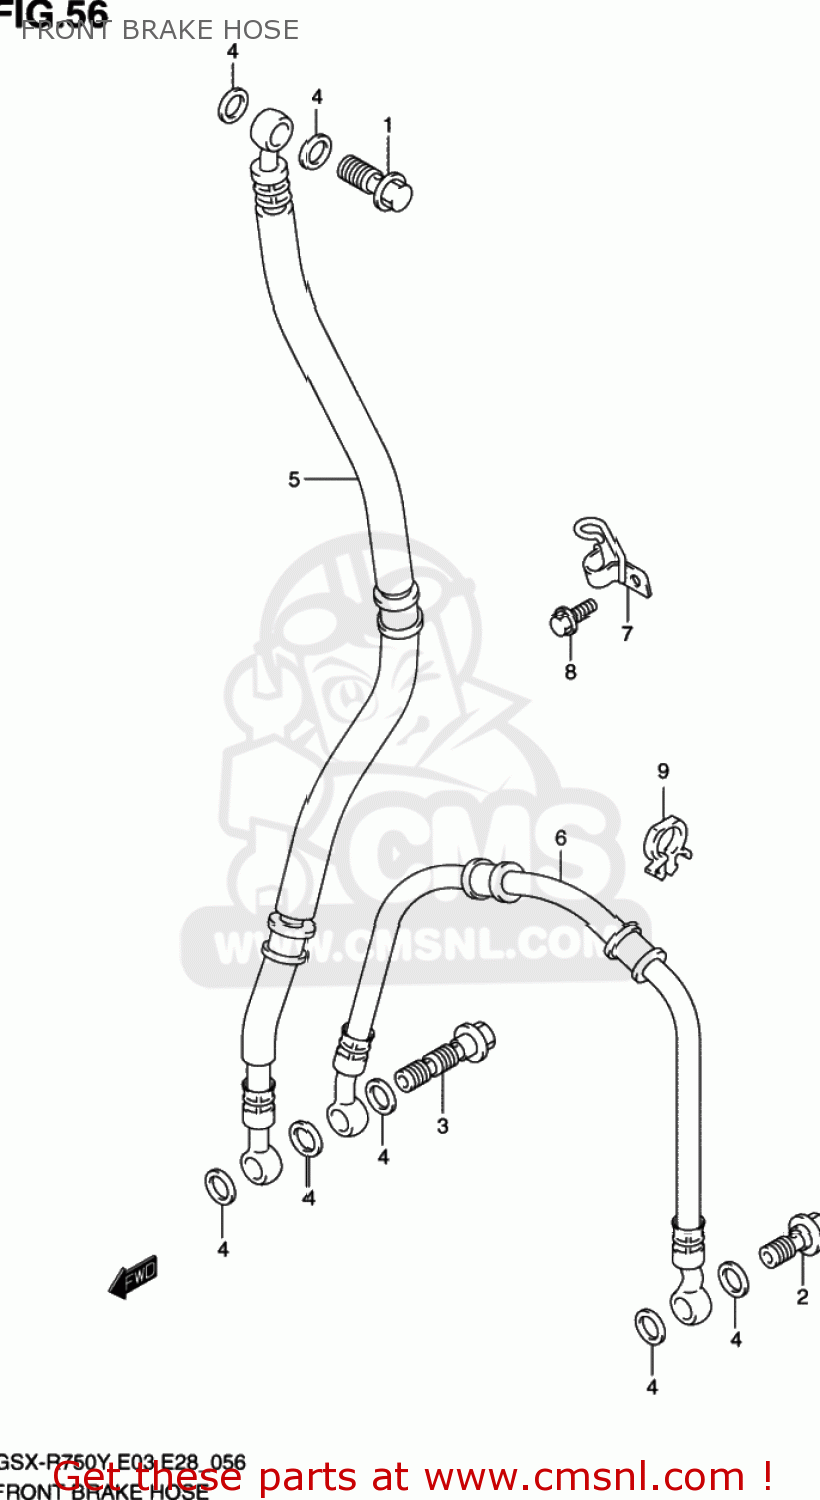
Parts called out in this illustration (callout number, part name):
1	BOLT UNION
2	BOLT UNION
3	BOLT UNION
4	WASHER(10X15X1.5)
5	HOSE,FR BRAKE NO.1
6	HOSE,FR BRAKE NO.2
7	CLAMP,FR BRAKE HOSE
8	BOLT
9	CLAMP
